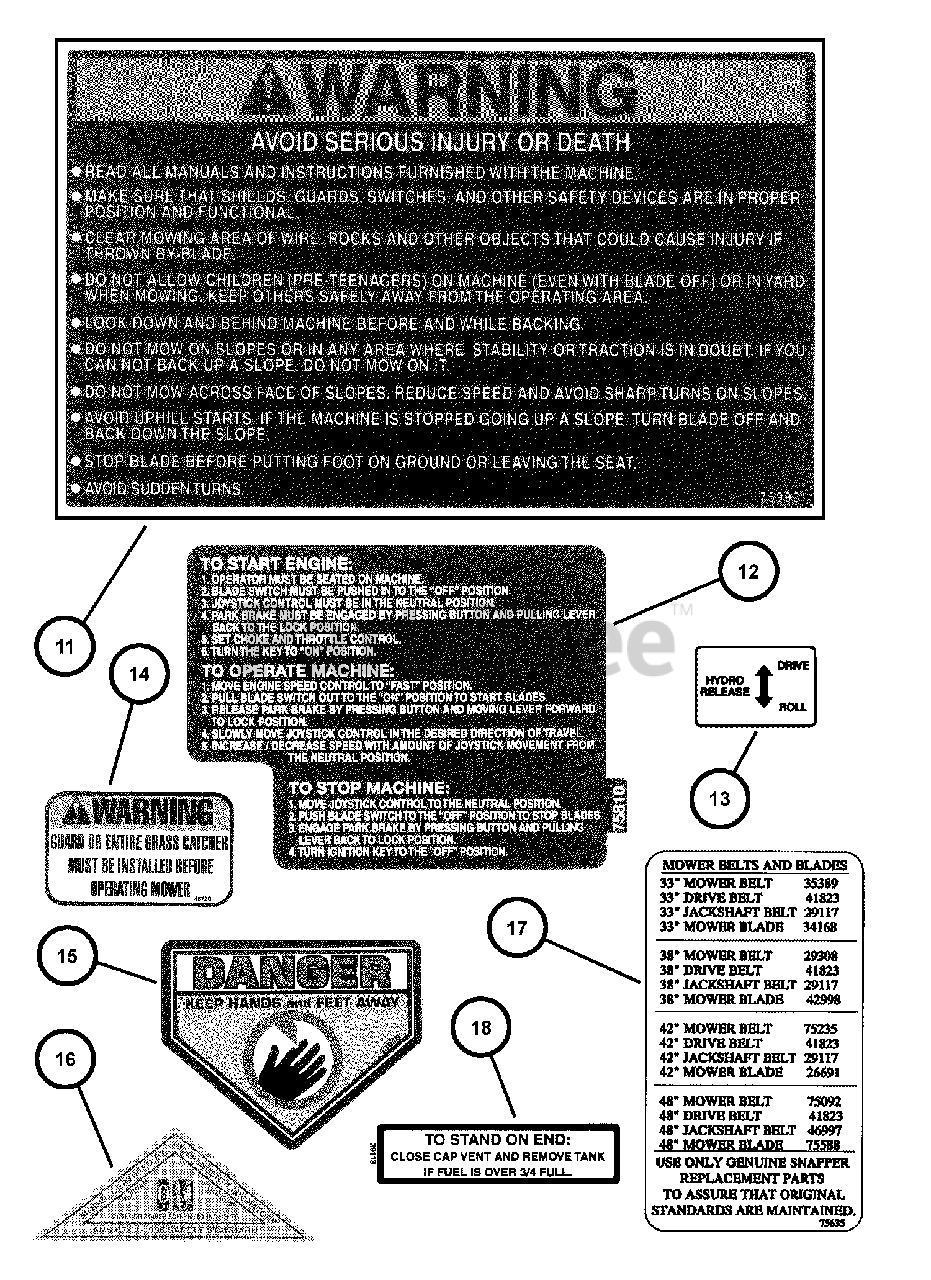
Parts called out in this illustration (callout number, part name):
11	DECAL, Warning, Read Manuals & Instructions
12	DECAL, Operating Instructions
13	DECAL, Hydro Release
14	DECAL, Chute/Deflector
15	DECAL, Danger, Cut Finger
16	DECAL OPEI Ride-On
17	DECAL, Service Parts, HOZ Domestic
18	DECAL, Caution, Fuel (English)
